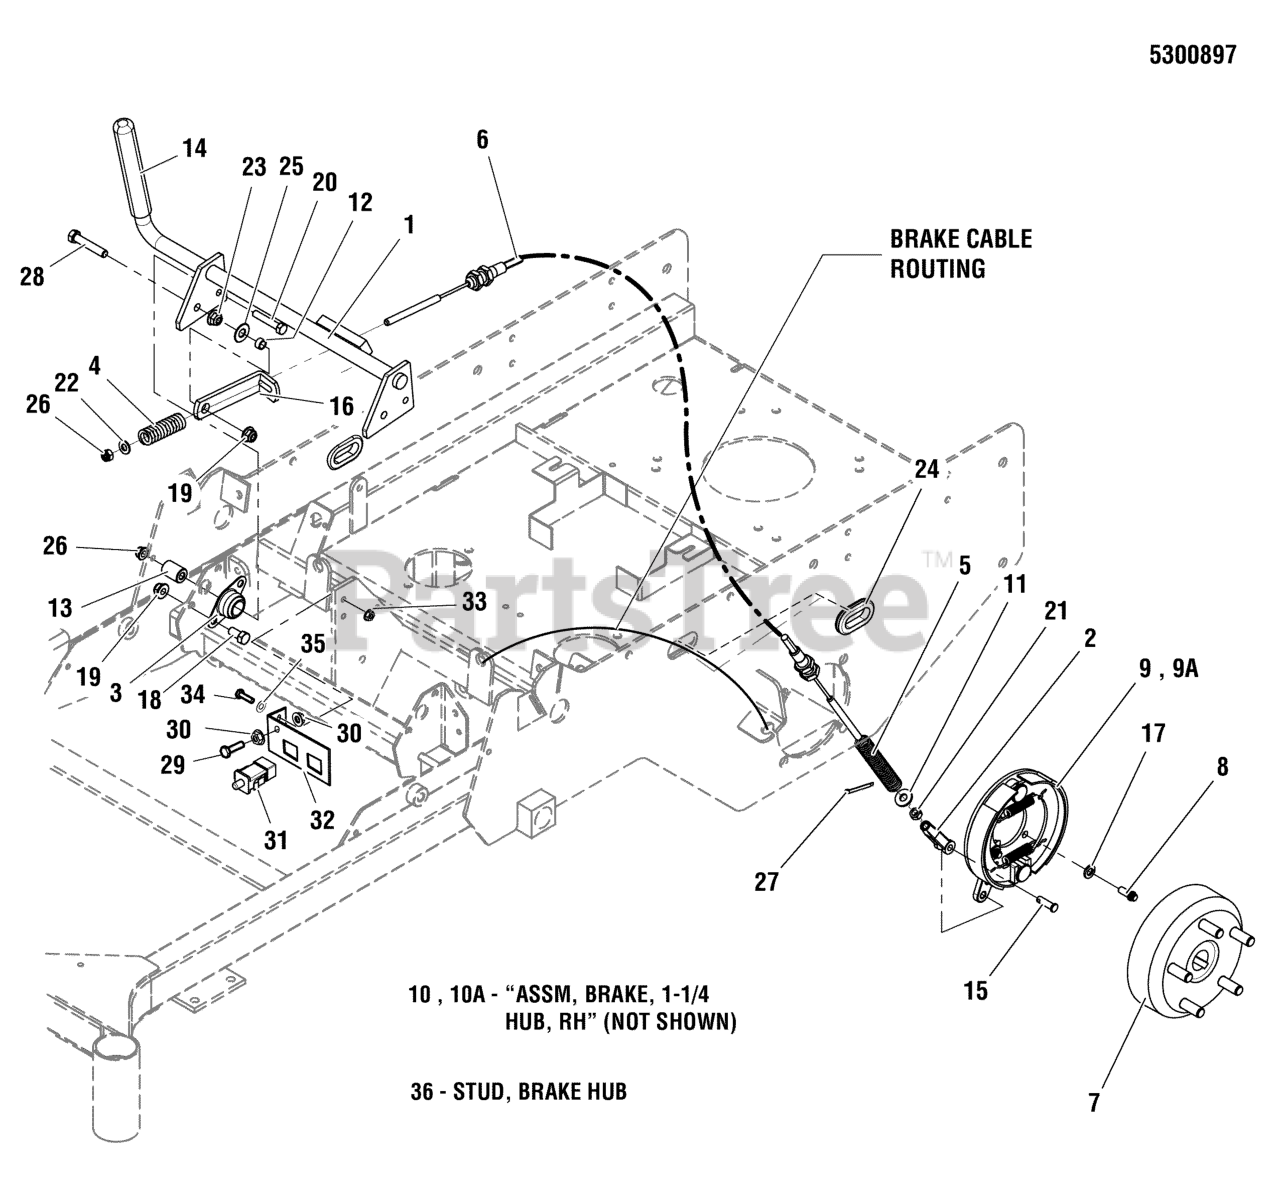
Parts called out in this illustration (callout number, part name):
1	WELD, BRAKE SHAFT, SNP 2552 - RED
2	CLEVIS, 5/16-24, PLASTIC
3	BEARING, BRONZE FLANGE, 3/4
4	SPRING, BRAKE
5	SPRING, COMPRESSION, 5-1/2
6	CABLE, PARKING BRAKE
7	BRAKE DRUM, 6", 5 BOLT, KNOTT
8	BOLT, 5/16-18 X 3/4 12PT FLANGE - PATCH
9	ASSM, BRAKE, 1-1/4 HUB, LH
9A	BRAKE SHOE ASM, LH, KNOTT
11	WASHER, 5/16 USS
12	SPACER, .38 X .50 X .27
13	SPACER, .32 X .75 X 1.06
14	GRIP, FOAM, 3/4 ID X 6 X .187
15	PIN, CLEVIS, 5/16 X 1 YZ
16	LINK, BRAKE LOCK - BLK
17	WASHER, 5/16 LOCK CZ
18	BOLT, 3/8-16 X 3/4" GD5 CZ
19	NUT, 3/8-16 HEX NYLOCK FLANGE
20	BOLT, 5/16-18 X 1-3/4 GD5 YZ
21	NUT, 5/16-24 HEX NYLON LOCK
22	WASHER, 5/16" SAE
23	NUT, 3/8-16 HEX SERRATED FLANGE
24	GROMMET, 1-1/4
25	WASHER, 3/8 SAE
26	NUT, 5/16-18 HEX NYLOCK FLANGE
27	PIN, COTTER, 1/8 X 1-1/4
28	BOLT, 3/8-16 X 1-1/2" GD5 CZ
29	BOLT, 5/16-18 X 1-1/4 GD5 YZ
30	NUT, 5/16-18 HEX SERRATED FLANGE (SMALL)
31	SWITCH, DP NO/NC SNAP-IN
32	BRACKET, SWITCH MOUNT
33	NUT, 1/4-20 HEX SERR. FLANGE
34	BOLT, 1/4-20 X 3/4 GD5 YZ
35	WASHER, 1/4 SAE
36	STUD, BRAKE HUB (SV)
